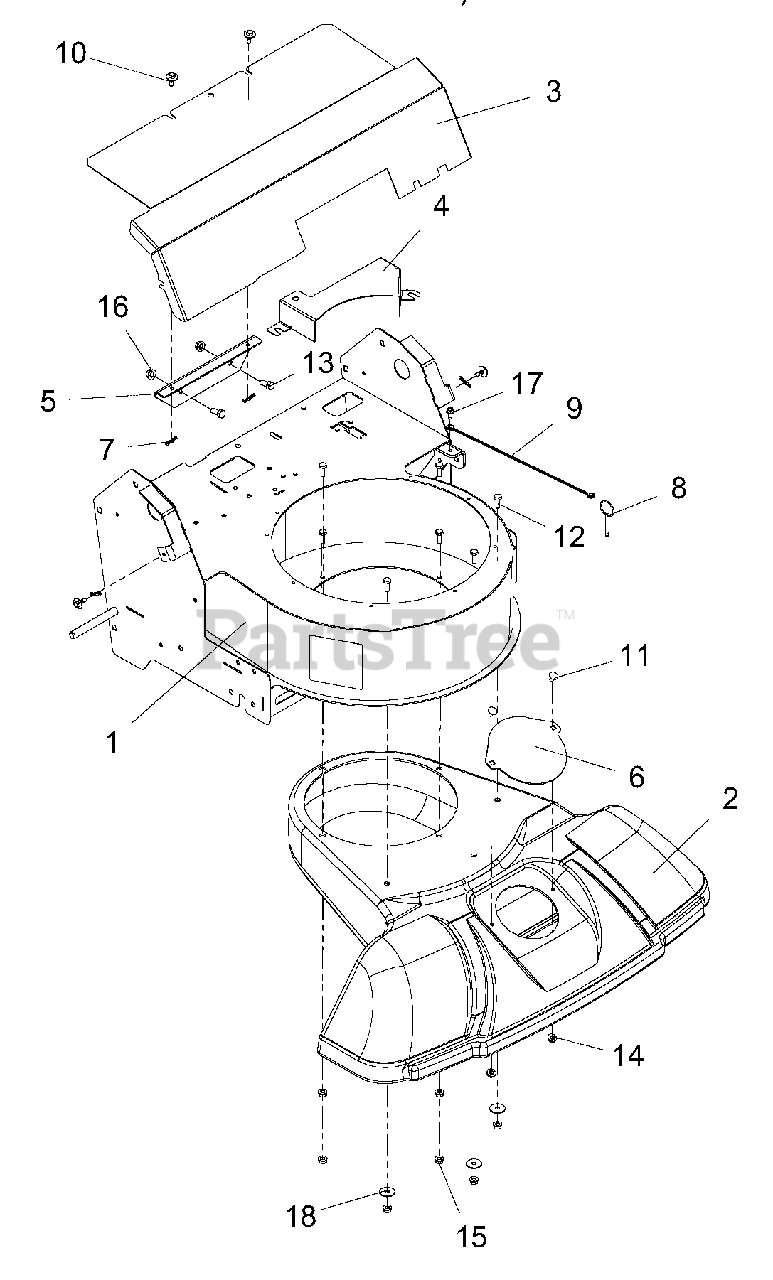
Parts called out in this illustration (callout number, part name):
1	WLDMT, FRAME - APV
2	INLET, UPPER
3	GUARD, TRANS - APV
4	GUARD, BELT - APV
5	BRKT, SUPPORT - TRANS GUARD
6	COVER, HOSE INLET - BLACK
7	PIN-HAIR, ENDRIES #25 YWZC
8	PIN, RING DETENT .25 x 1.25
10	SCR, TAP .25-20 x .5 CAPTIVE
11	BLT-RDHDSQSHNK .25-20 x .50 YWZC
12	BLT-HEX .25-20 x .75 GR5 YWZC
13	BLT-HEX .31-18 x .75 GR5 YWZC
14	NUT, LK-CTR-FLG .25-20 YWZC
15	NUT, LK-TOP-FLG .25-20 YWZC
16	NUT, LK-TOP-FLG .312-18 YWZC
17	SCR-TAP .25-20 x .50 HWH TR YWZ
18	WSHR-FL-STL .281 x 1.000 x .063 YWZC
